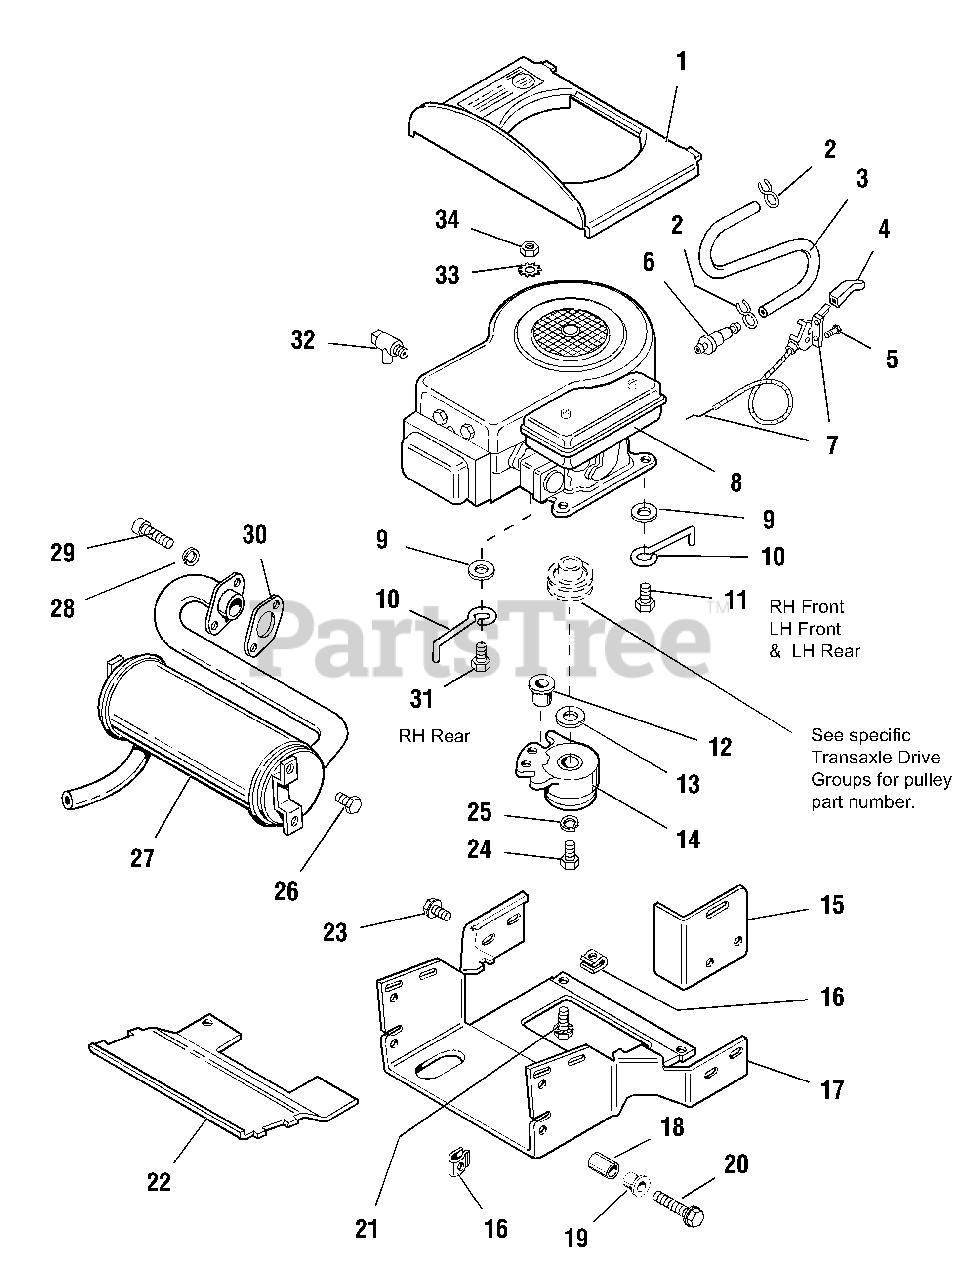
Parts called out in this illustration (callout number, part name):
1	PLENUM
2	CLAMP, Hose
3	HOSE, Fuel, Cut to 12" length
3	HOSE, Fuel, Cut to 9-1/8" length
4	KNOB, Throttle Control
5	SCREW, Plastite, 1/4-10 x 5/8
6	FILTER, Fuel
7	CONTROL ASSY., Throttle
8	ENGINE, 14HP or 16HP Briggs & Stratton
9	WASHER
10	GUIDE, Belt, Wireform
11	SCREW, Hex Hd., Taptite, 3/8-16 x 1-1/5
11	SCREW, Hex Hd., Taptite, 3/8-16 x 1-1/4
12	SLEEVE, Clutch Anchor
14	CLUTCH, Electric
15	PLATE, Muffler Duct
16	PAL NUT, 5/16-18
17	DUCT, Muffler, Lower
19	PIVOT, Hood
20	SCREW, Hex, Whiz, 5/16-18 x 1-1/4
21	SCREW, Hex, Flange Whiz, 5/16-18 x 3/4
22	DUCT, Muffler, Upper
23	SCREW, Taptite, 5/16-18 x 1/2
24	CAPSCREW, Hex, 7/16-20 x 2-1/2
25	LOCKWASHER, 7/16
26	SCREW, Taptite, 1/4-20 x 3/8
27	MUFFLER ASSY.
28	LOCKWASHER, 5/16
29	CAPSCREW, Socket Hd., 5/16-18 x 3/4
30	GASKET, Muffler
31	SCREW, Hex Hd., Taptite, 3/8-16 x 1-1/2
31	SCREW, Hex Hd., Taptite, 3/8-16 x 2.0
32	DRAIN VALVE, Oil
33	WASHER, External Tooth 3/8
34	NUT, Hex, Jam Lock, 3/8-16
